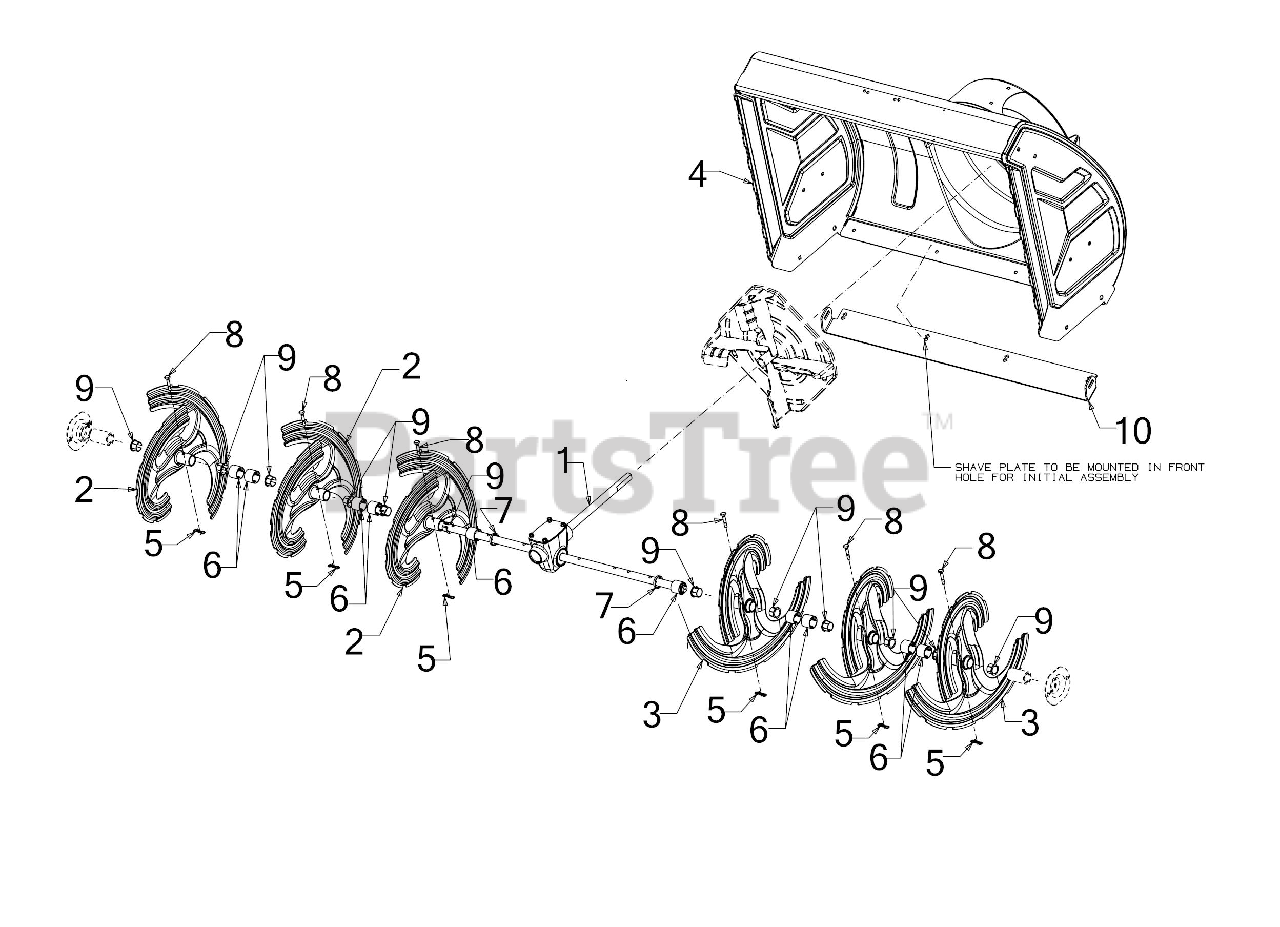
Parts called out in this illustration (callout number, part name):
1	34" AUGER GEARBOX ASSEMBLY
2	14" AUGER SPIRAL ASSEMBLY (RH)
3	14" AUGER SPIRAL ASSEMBLY (LH)
4	34" AUGER HOUSING ASSEMBLY
5	BOW TIE COTTER PIN 1/4-5/16
6	SPACER 1.25OD x .75ID X1.00 LG
7	SPCR 1.25 OD x 75IDX2.00LG
8	SHEAR PIN .25 x 1.50 GR2
9	FLANGE BUSHING
10	33.50" SHAVE PLATE
